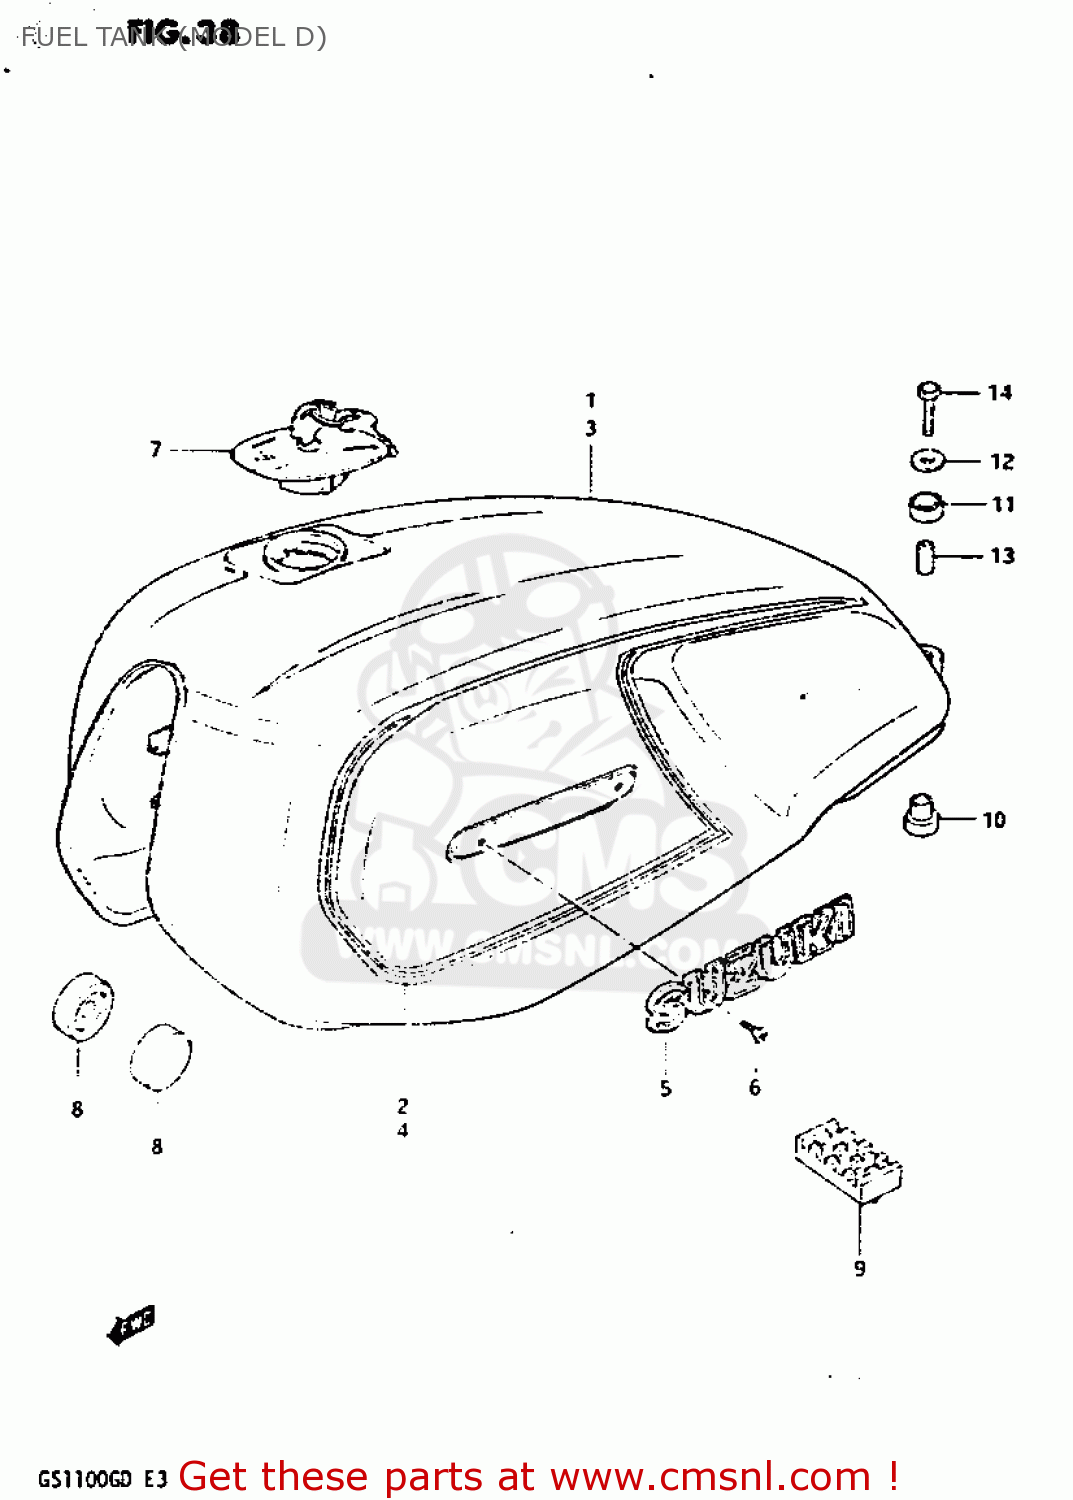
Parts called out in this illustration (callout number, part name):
1	TANK ASSEMBLY,FUEL
2	TAPE SET,FUEL TANK
3	TANK ASSEMBLY,FUEL
4	TAPE SET,FUEL TANK
5	EMBLEM
6	SCREW 3X6
7	CAP SET,FUEL TANK
8	CUSHION
9	CUSHION,FUEL TANK
10	CUSHION
11	CUSHION
12	WASHER (6.5X24X1.6)
13	SPACER (6.4X9X21.5)
14	BOLT
